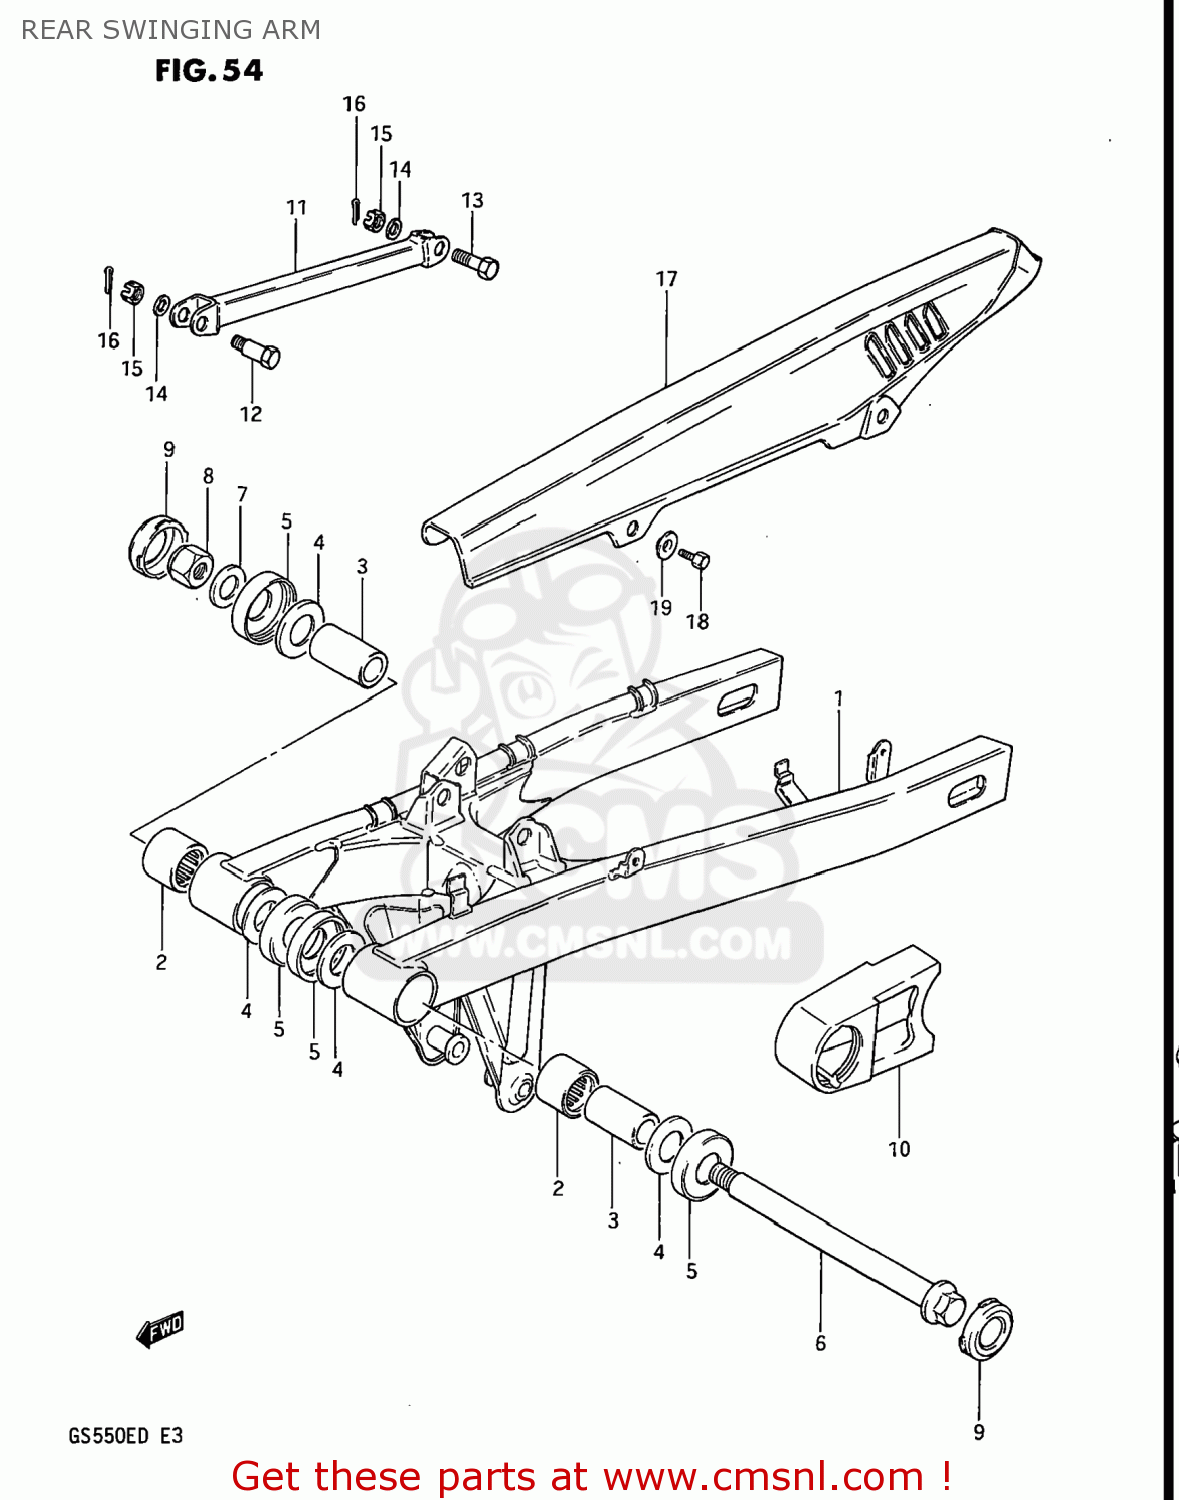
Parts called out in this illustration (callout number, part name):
1	SWING ARM ASSEMBLY,REAR
2	BEARING(25X33X30)
3	SPACER,RR SWGARM PIVOT
4	WASHER
5	COVER,RR SWGARM DUST SEAL
6	SHAFT,REAR SWING ARM
7	WASHER
8	NUT 14MM
9	CAP,SWINGINGARM PIVOT
10	BUFFER,CHAIN TOUCH DEFLECTOR
11	TORQUE LINK,REAR
12	BOLT
13	BOLT
14	WASHER
15	NUT
16	PIN 20X20
17	CASE,CHAIN
18	BOLT
19	WASHER
